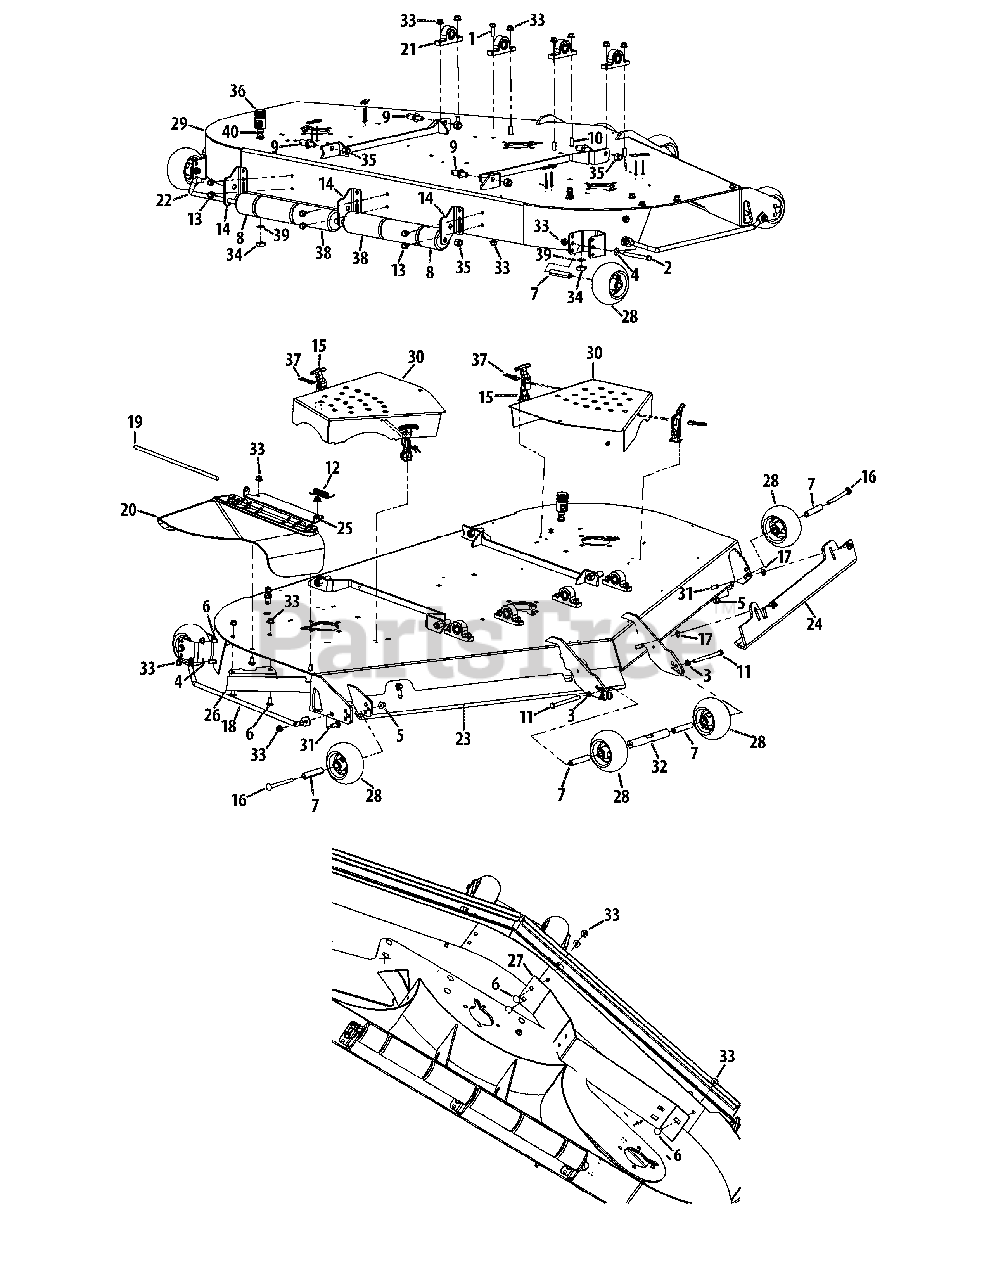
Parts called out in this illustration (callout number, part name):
1	Hex Cap Screw, 3/8-16, 1.25
2	Hex Cap Screw, 3/8-16, 4.00
3	Lock Washer, 3/8
4	Flat Washer, 3/8
5	Flange Lock Hex Nut, 3/8-16
6	Carriage Bolt, 3/8-16 x .75
7	Wheel Spacer
8	Grass Catcher Roller
9	Pin, 5/8 Dia. x 1.2
10	Carriage Screw, 3/8-16 x 1.25
11	Hex Cap Screw, 3/8-16 x 4.50
12	Torsion Spring, 0.4 x 2.16
13	Hex Washer Screw, 3/8-16, .5
14	Deck Roller Mount Bracket
15	T-Handle Latch Draw
16	Carriage Bolt, 3/8-16 x 4.00
17	Push Retainer
18	Finger Guard
19	Pin, .375 x 14.06
20	Chute Deflector
21	Pillow Block, Steel
22	J-Hook w/ Threaded Roller
23	Right Hand Front Adjustment Skirt
24	Left Hand Front Adjustment Skirt
25	Chute Deflector Bracket
27	Baffle, 72" Adjustment
28	Complete Wheel, 5.00 Dia.
29	72" Deck Assembly
30	Deck Belt Cover
31	Carriage Bolt, 3/8-16 x 1
32	Ball Wheel Mounting Shaft
33	Flange Lock Hex Nut, 3/8-16
34	Hex Nut, M16-1.5
35	Lock Nut, Nylon Insert, 1/2-13
36	Water Nozzle Adaptor
37	Pop Rivet, 3/16
38	Front Roller
39	Lock Washer, 17 x 23.8 x 1.95
40	Deck Water Nozzle
